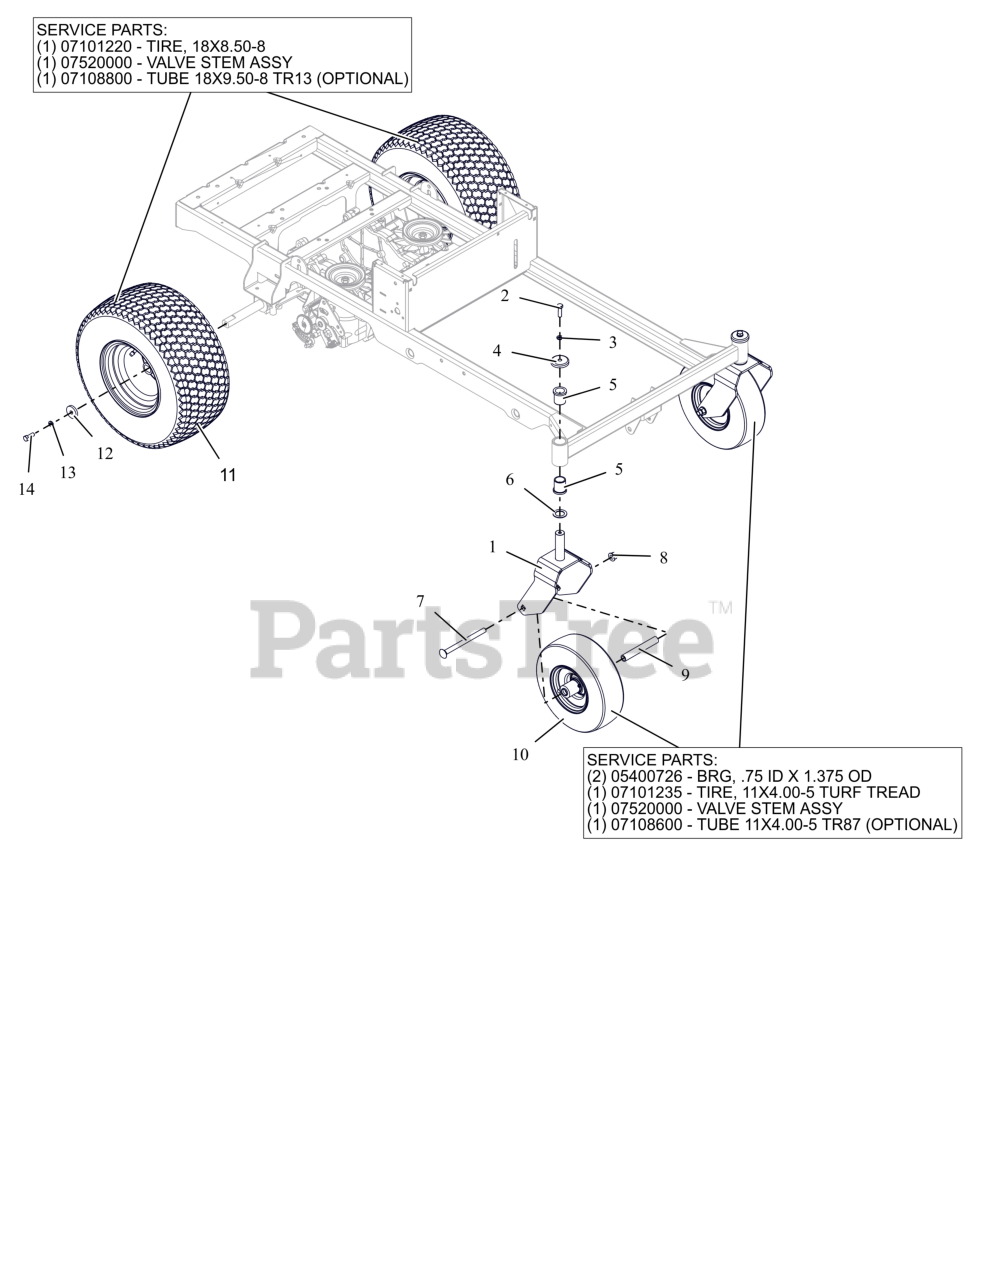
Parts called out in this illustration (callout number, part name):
1	WLDMT- CASTER FORK
2	BLT- HEX .38-16X1.25 G5 ZB500
3	WSHR-LK-REG .375X.094 ZB500
4	SHIELD- AXLE BEARING BLK
5	BSHG-FLG 1.00X1.25X1.50X1.50
6	WSHR-HRD-THRS 1.007X1.542X.062
7	BLT, RHSN .50-13X6.50 G5 ZCC
8	NUT-LK-CTR-FLG .500-13 GG ZCC
9	SPACER, ROLLED WHEEL
10	ASM- WHL/TIRE 11X4.00-5 LG BLK
10	BRG, .75 ID X 1.375 OD
10	LAWN TIRE FRONT, 11/4-5 TURF TREAD
10	VALVE STEM ASS'Y
10	TIRE TUBE, 11/4.0-5 4 PLY TR87 90 BENT VALVE
11	ASM-WHL/TIRE 18 X 8.5-8 LG BLK
11	LAWN TIRE REAR, 4 PLY K500 18/8.50-8
11	VALVE STEM ASS'Y
11	TIRE TUBE 18/6.50/8.50/9.50-8, 20/8.00/10.00-8 4 PLY TR13 STRAIGHT VALVE
12	WSHR, FLT .406X1.50X.245 ZCC
13	WSHR,LK-REG .375X.094 ZCC
14	BLT, HEX .38-16X1.00 G8ZCCEP30
